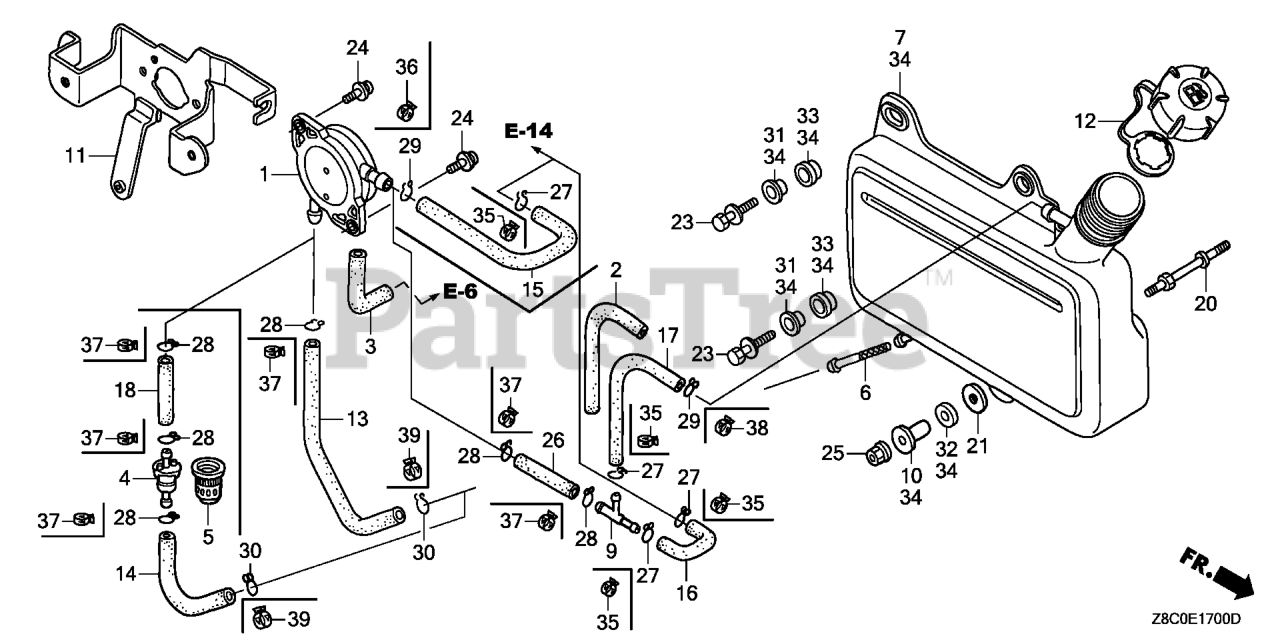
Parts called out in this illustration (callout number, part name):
1	PUMP ASSY., FUEL (MSDS)
3	TUBE, DIAPHRAGM
6	FILTER, FUEL
7	TANK, FUEL
10	COLLAR, FUEL TANK SETTING
11	STAY A, FUEL TANK
12	CAP ASSY., FUEL TANK
13	TUBE, FUEL TANK (FKM)
15	TUBE, FUEL (FKM)
20	BOLT, FUEL TANK STUD (H=30MM)
21	WASHER (6MM)
23	BOLT-WASHER (6X25)
24	SCREW-WASHER (5X14)
25	NUT, FLANGE (6MM)
31	COLLAR, TANK SET
32	RUBBER A, TANK MOUNTING
33	RUBBER B, TANK MOUNTING
35	CLIP, TUBE (D8)
36	CLIP, TUBE (D8.5)
37	CLAMP, TUBE (D10)
39	CLAMP, TUBE (D12)
